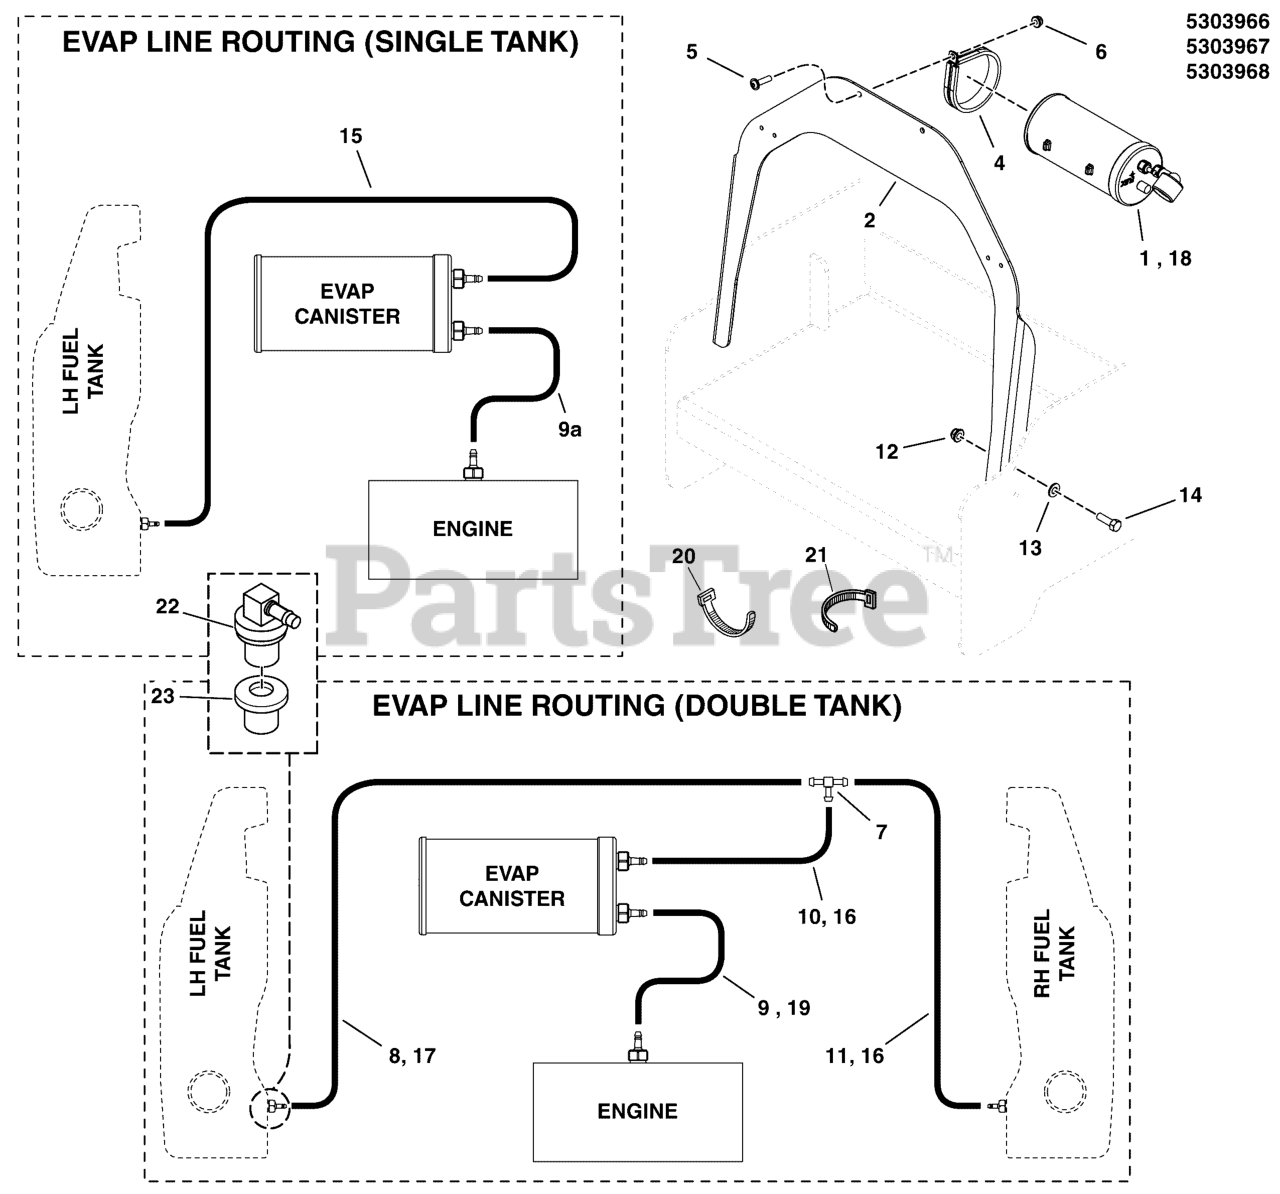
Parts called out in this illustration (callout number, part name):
1	CNSTR, CARB, 6 GAL
2	BRACKET, CARB CANISTER, S50X - BLK
3	DECAL, EPA CERT, ZTRS
4	CLAMP, 3" ID, CUSHIONED, STAINLESS
6	NUT, 1/4-20 HEX NYLOCK FLANGE
7	FITTING, 3/16" TEE, BARB TYPE, HDPE
8	HOSE, VAPOR, 5MM ID, 43.00 LG
9	HOSE, VAPOR, 5MM ID, 36.00 LG
10	HOSE, VAPOR, 5MM ID, 5.50 LG
11	HOSE, VAPOR, 5MM ID, 11.00 LG
12	NUT, 5/16-18 HEX NYLOCK FLANGE
13	WASHER, 5/16" SAE
14	BOLT, 5/16-18 X 1 GD5 YZ
15	HOSE, VAPOR, 5MM ID, 19.00 LG
16	HOSE, VAPOR, 5MM ID, 15.00 LG
17	HOSE, VAPOR, 5MM ID, 39.00 LG
18	CNSTR, CARB, 9 GAL
19	HOSE, VAPOR, 5MM ID, 22.5.00 LG
20	TIE, SELF-LOCKING, 12"
21	TIE, SELF-LOCKING, 6"
22	REMOTE VENT ASSEMBLY
23	GROMMET
